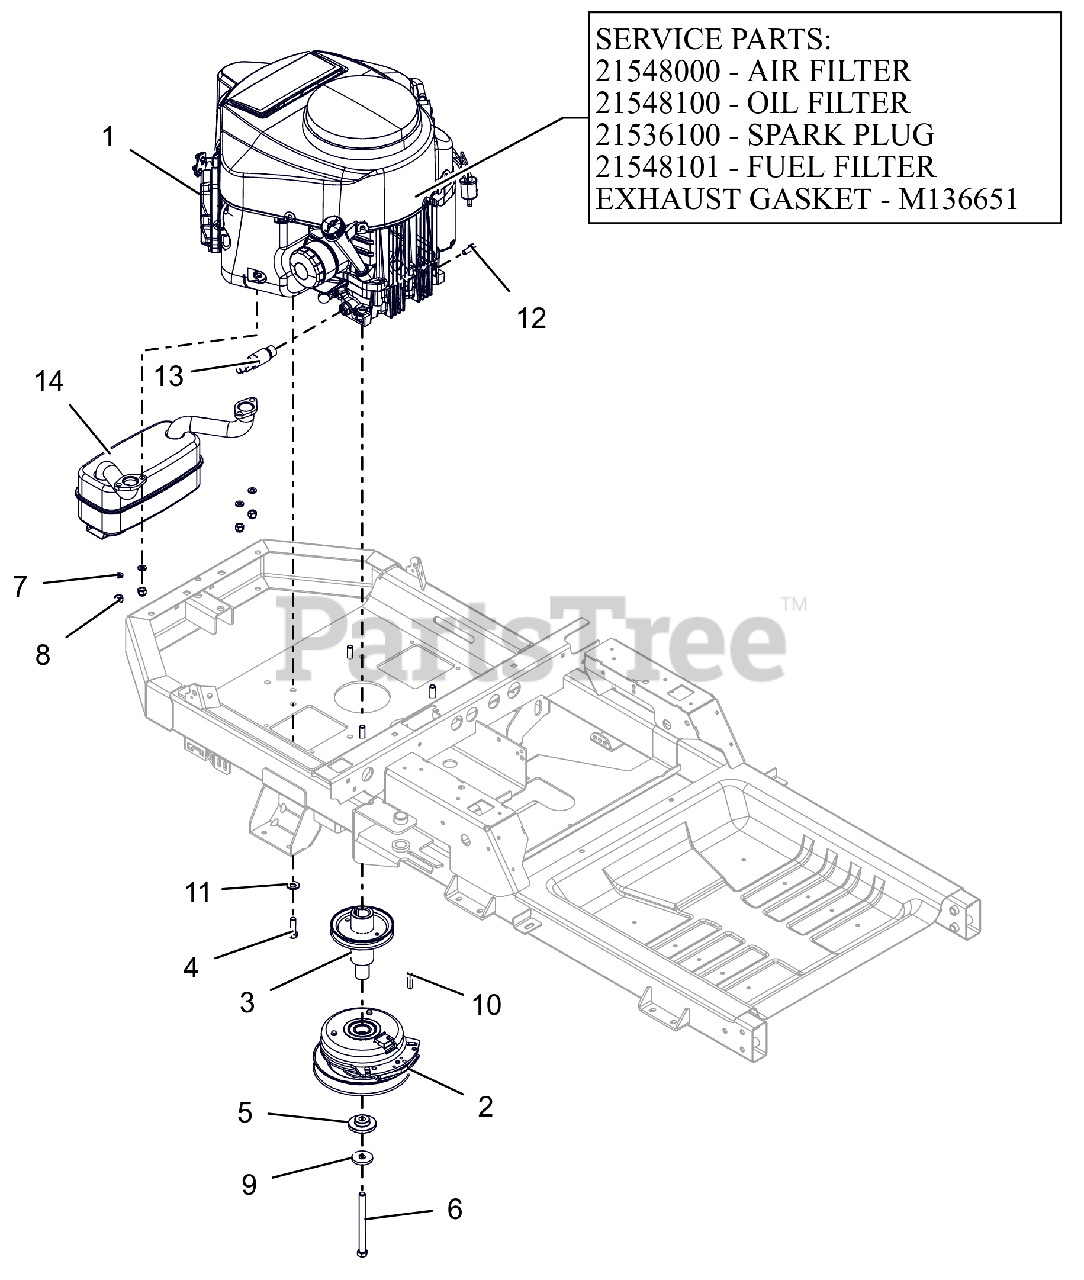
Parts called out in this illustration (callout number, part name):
1	ENGINE, KAWASAKI FR651V 21.5HP
1	AIR FILTER, KAWASAKI FR
1	OIL FILTER, KAWASAKI FR
1	PLUG, SPARK
1	FUEL FILTER-KAWASAKI FR
1	GASKET, MUFFLER #
2	CLUTCH,105FTLB MONOPOLE 6.83"
3	WLDMT, DRIVE SHEAVE (LG XL)CZC
4	BLT, HEX .38-16X1.25 G5 ZCC NT
5	BSHG-FLG .469X1.06X.574X2.0
6	BLT-HEX.438-20X5 GR8 YZ NYTORQ
7	WSHR,LK-REG .312X.078 ZCC
8	NUT,NYL M8-1.25 G8.8 ZCC
9	WASHER, 7/16" SPRING DISK
10	KEY-SQ .25 X 1.25 X .25 SAE
11	WASHER, 3/8" SPRING DISC
12	BLT, HEX M8-1.25X20 G8.8 ZCC
13	DRAIN, OIL M20X2.5
14	MUFFLER - KAWASAKI
